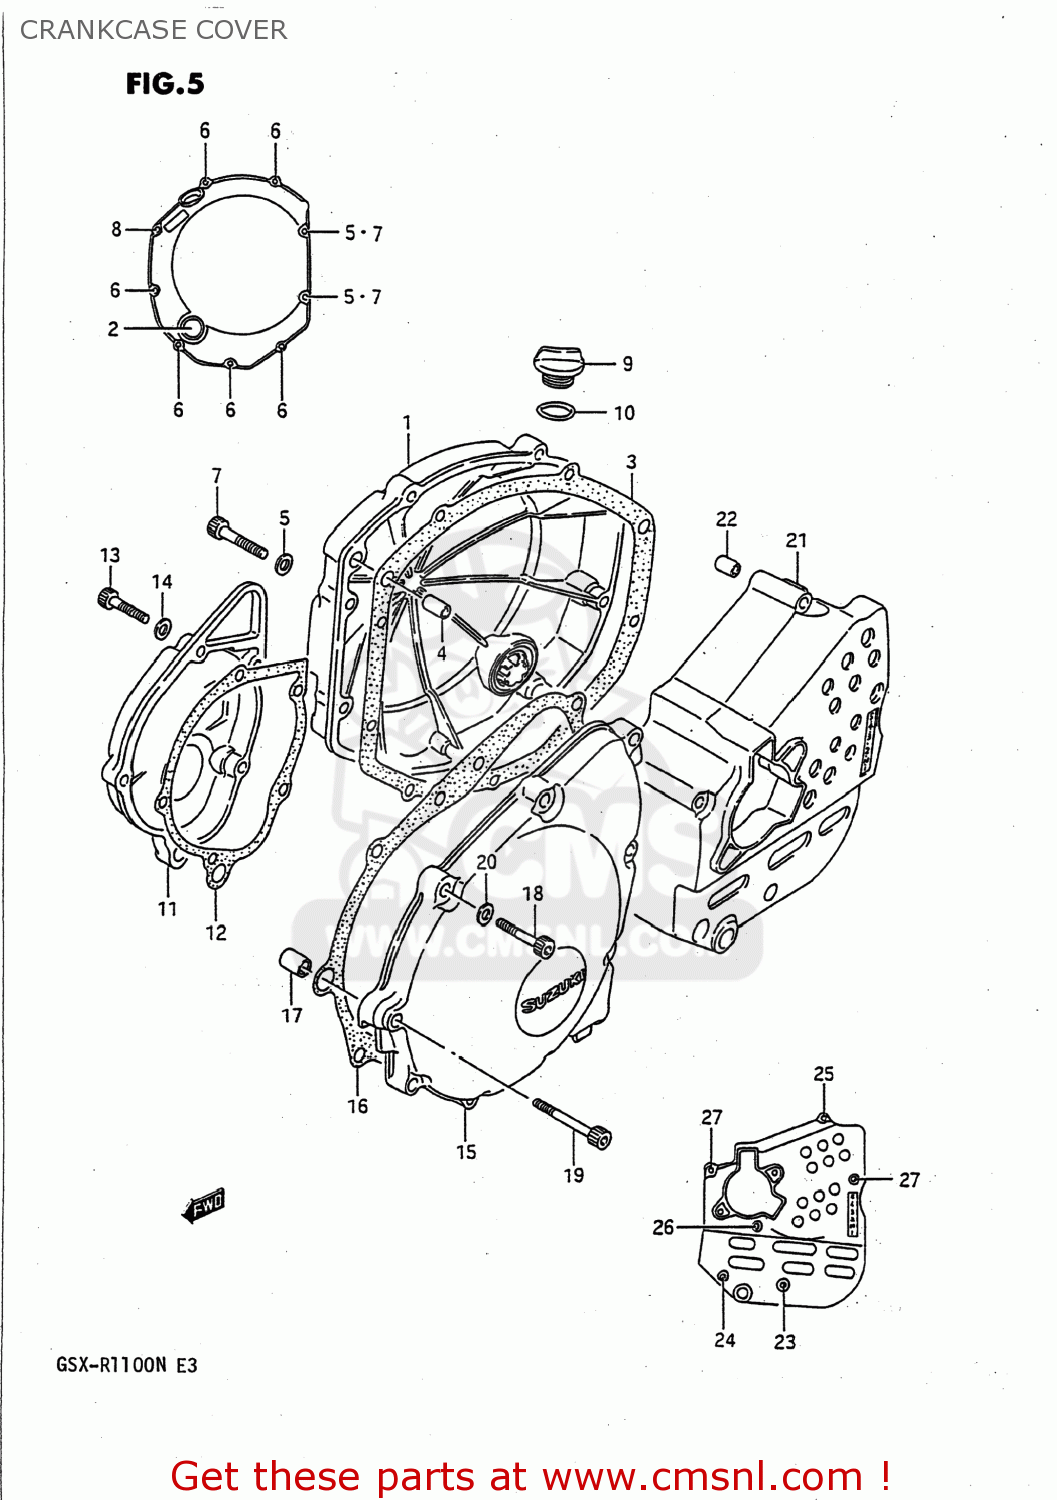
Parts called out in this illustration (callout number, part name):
1	COVER,CLUTCH
2	LENS,OIL LEVEL CHECK
3	GASKET,CLUTCH COVER (NAS)
4	PIN
5	GASKET(5.8X11X1.2) (NAS)
6	BOLT
7	BOLT
8	BOLT
9	PLUG
10	O RING(D:3.1,ID:16.8)
11	COVER,SIGNAL GENERATOR
12	GASKET,SIGNAL GENERATOR COVER (NAS)
13	BOLT
14	GASKET(5.8X11X1.2) (NAS)
15	COVER,STARTER GEAR
16	GASKET,STARTER GEAR COVER (NAS)
17	PIN (11X20)(SUS)
18	BOLT
19	BOLT
20	GASKET(5.8X11X1.2) (NAS)
21	COVER,ENGINE SPROCKET
22	PIN
23	BOLT
24	BOLT
25	BOLT
26	BOLT
27	BOLT
